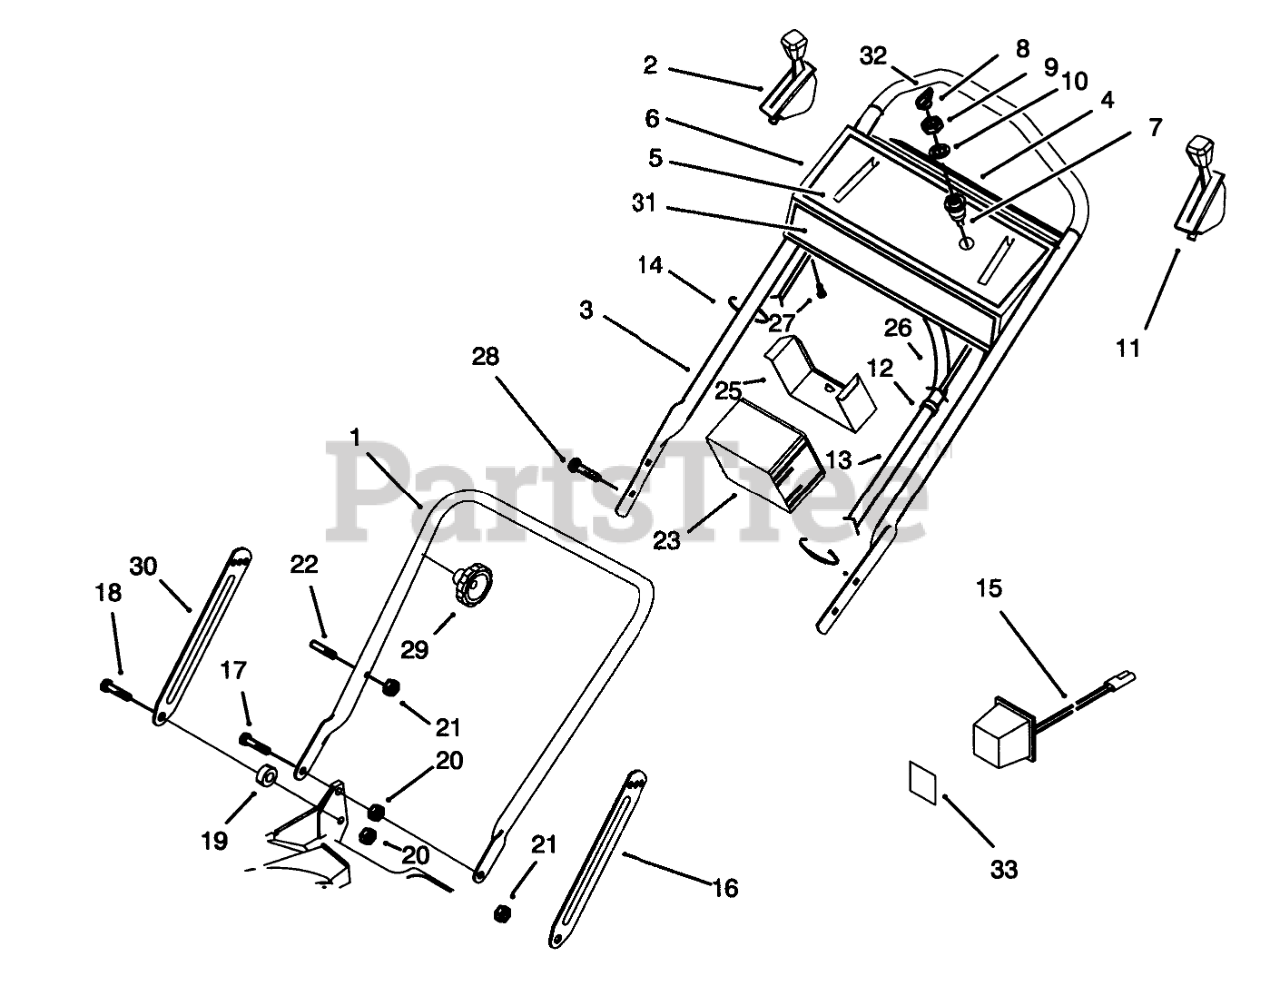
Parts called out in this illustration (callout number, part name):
1	LOWER HANDLE ASM
2	CONTROL-SPEED, GROUND
3	Handle-Upper
4	DECAL - PANEL, REAR
5	DECAL - INSTRUCTION
6	Panel-Control (Incl. Ref. #4, 5, & 31)
7	STARTER SWITCH ASM
8	KEY-IGNITION
9	NUT-HH
10	WASHER-TOOTH, INTERNAL
11	THROTTLE CONTROL
12	FITTING-RING
13	CONTROL CABLE COVER
14	TIE-CABLE
15	Charger-Battery
16	Latch-Handle
17	SCREW-SHOULDER
18	SCREW-SHOULDER
19	SPACER
20	NUT-LOCK, NI
21	NUT-LOCK, NI
22	HANDLE PIN
23	BATTERY ASSEMBLY
25	Retainer-Battery
26	Harness-Wire
27	10-16X1/2 SHWH SCREW
28	SCREW-HANDLE
30	Latch-Handle
31	DECAL - FRT PANEL
32	Grip-Foam
33	DECAL - CAUTION F/W
